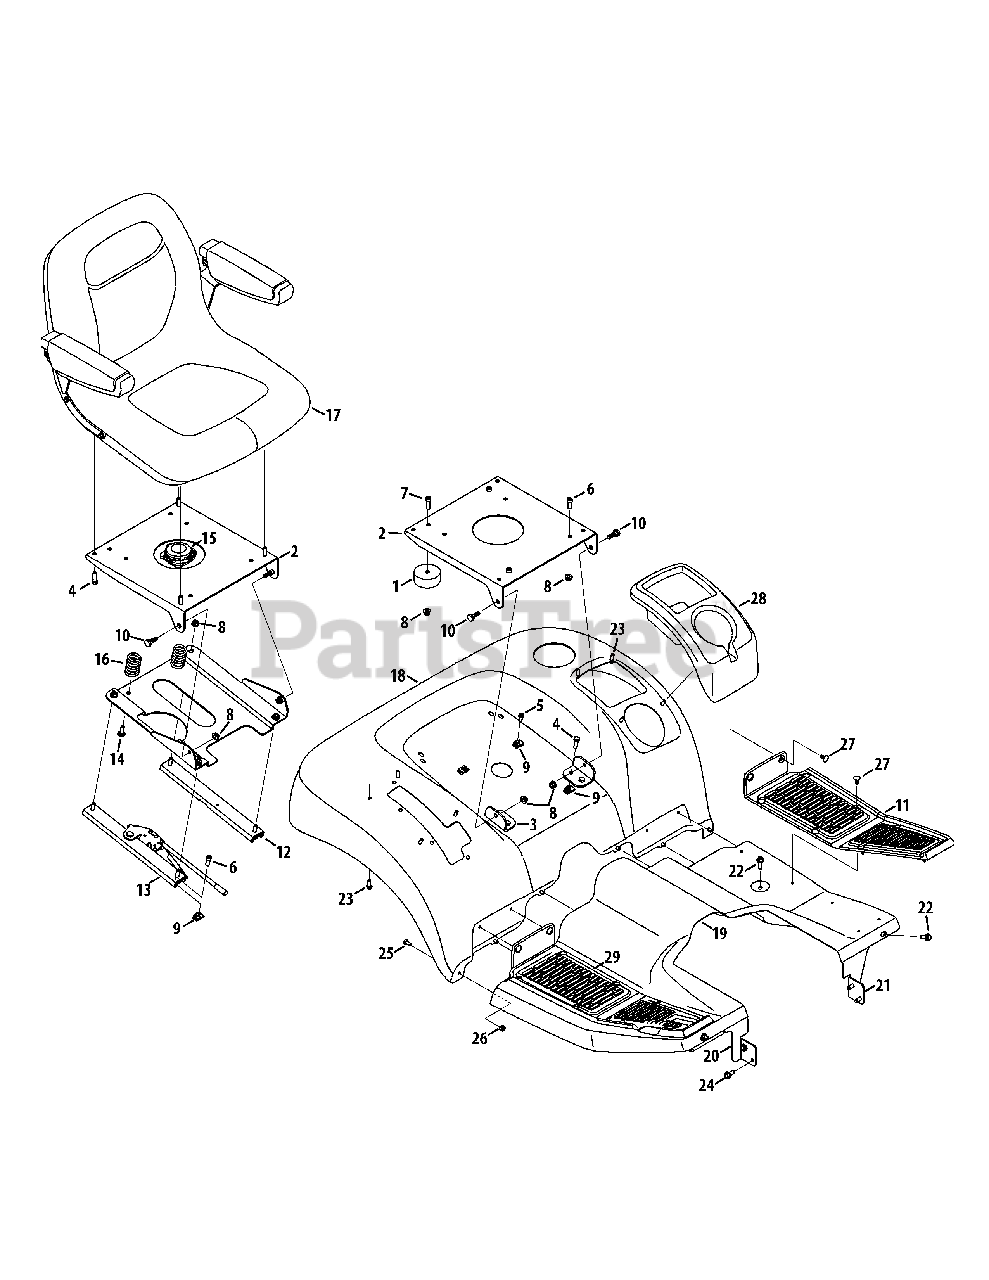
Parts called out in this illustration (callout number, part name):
1	Bumper, 2.50 x 1.13
2	Seat Mount Plate
3	Suspension Seat Front Pivot Bracket
4	Hex Screw, 5/16-18 x 1.00
5	Hex Flange Screw, 5/16-18
6	Socket Screw, 5/16-18 x .750
7	Socket Screw, 5/16-8 x 1
8	Flange Lock Nut, 5/16-18
9	U-Nut, 5/16-18
10	Shoulder Screw, 5/16-18 x .437 x .268
11	LH Floor Pad
12	Seat Track w/o Latch
13	Seat Track w/ Latch
14	Carriage Screw, 5/16-18 x 1.00
15	Seat Switch, 1/4
16	Compression Spring
18	Fender
19	Running Board
20	RH Running Board Bracket
21	LH Running Board Bracket
22	Hex Washer Screw, 5/16-18 x 1.000
23	Hex Washer Screw, 1/4-15 x .750
24	Hex Washer Screw, 5/16-18 x .750
25	Hex Screw, 1/4-20 x .50
26	Hex Lock Nut, 1/4-20
27	Ratchet Clip, .250
28	LH Cup/Compartment Cover
29	RH Floor Pad
